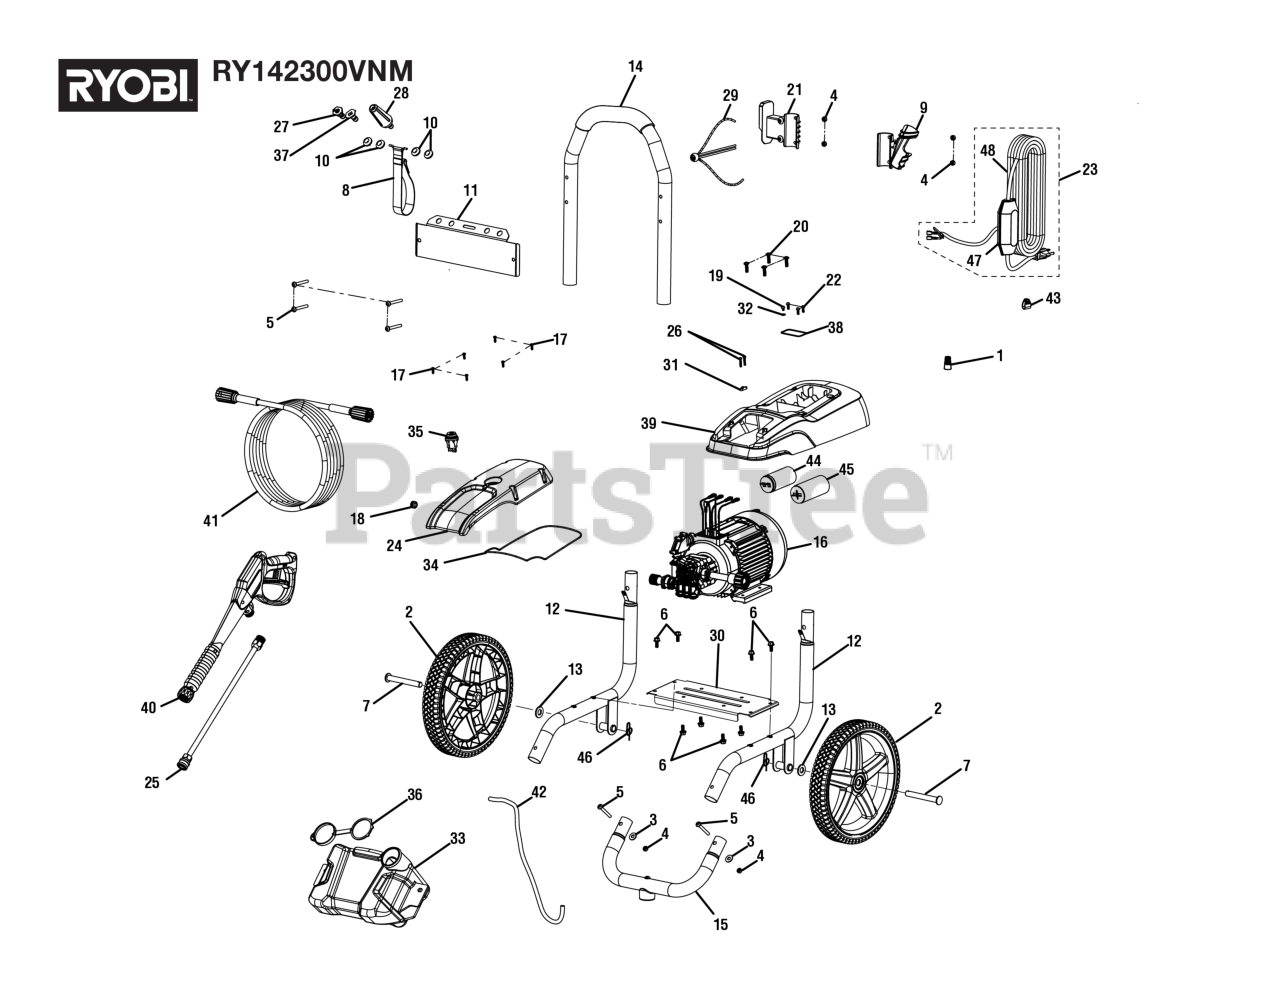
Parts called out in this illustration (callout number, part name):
1	Tuerca para alambre
3	Washer (1/4 in.)
4	Lock Nut (M6 x 1)
5	Screw (M6 x 1 x 48 mm, T30 Torx Pan Hd.)
6	Flange Bolt (M6 x 1 x 16 mm, Hex Hd.)
8	Hose Holder Strap
9	Trigger Handle Holder
10	Rubber Nozzle Grommet
11	Face Panel
12	Frame Assembly
13	Washer (1/2 in.)
14	Handle Assembly
15	Frame Assembly (Front)
17	Screw (M4.2 x 15 mm, Phillips Hd. S.T.)
18	Soap Tank Grommet
19	Screw (M4 x 16 mm, Pan Hd.)
20	Bolt (M6 x 20 mm, Philips Pan Hd.)
21	Cord Holder
22	Bolt (M4 x 12 mm, Pan Hd.)
23	Power Cord Assembly
24	Switch Cover
25	Spray Wand Assembly
26	Screw (M3.5 x 20 mm, Button Hd.)
27	15deg Nozzle
28	Turbo Nozzle
29	Power Cord Strap
30	Motor Plate
31	Cord Clamp
32	Toothed Lock Washer (M4)
33	Detergent Tank
34	Rubber Gasket
35	On/Off Switch
36	Detergent Tank Cap
37	Soap Nozzle (Blue)
38	Wire Box Gasket (Lower)
39	Motor Shroud
40	Trigger Handle
41	High Pressure Hose
42	Chemical Siphon Tube
43	Electric Cord Clip
44	Capacitor (CBB60 SH PO 250 VAC 120UF)
45	Capacitor (CD60 250 VAC 300UF)
46	Hitch Pin
47	Grounded Plug
48	Electrical Wire
